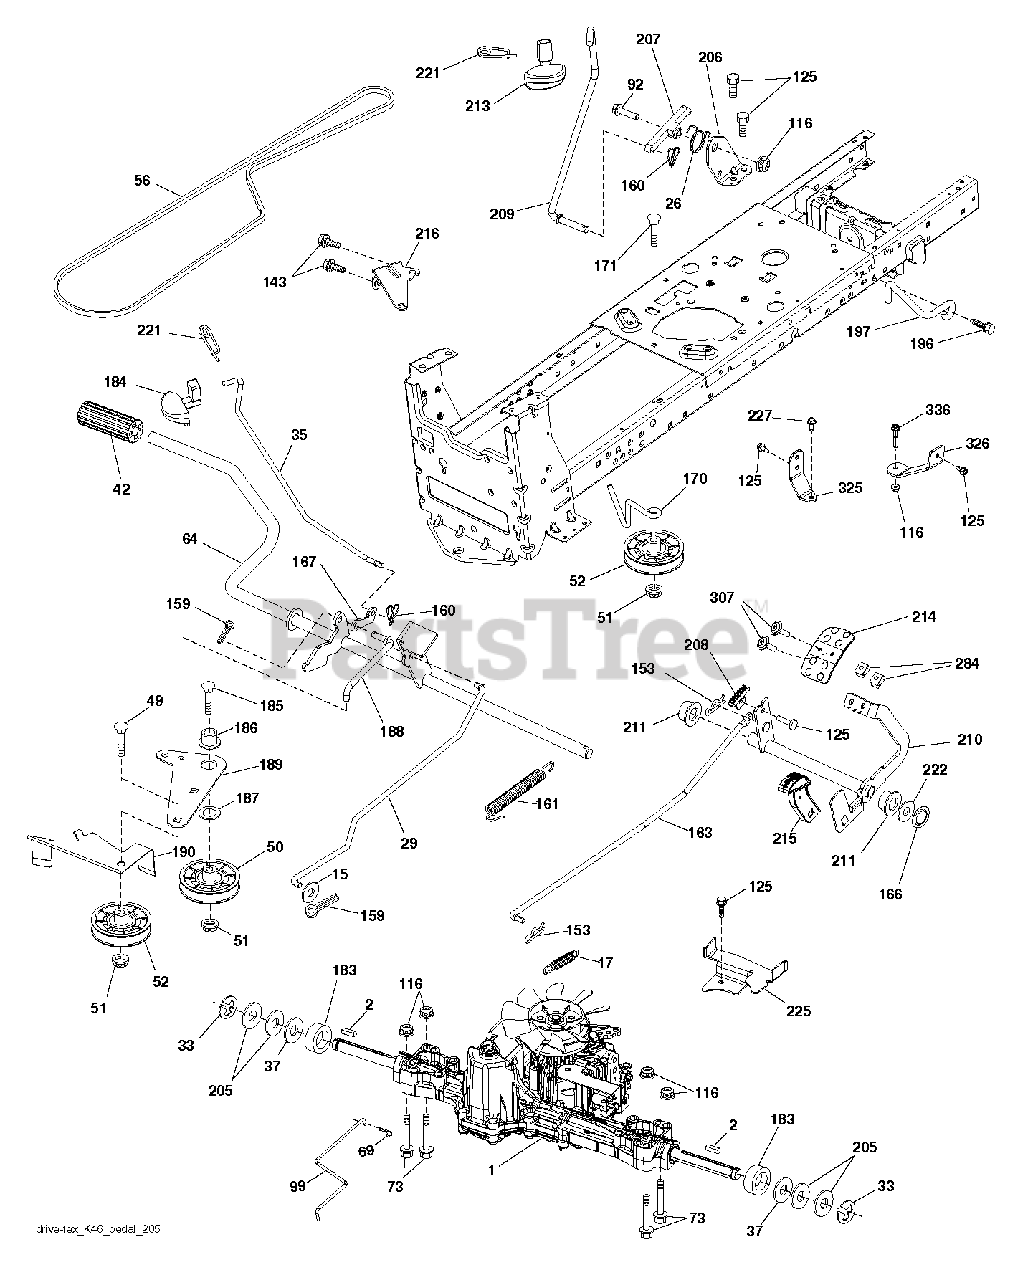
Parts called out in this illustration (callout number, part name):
2	SQUARE KEY
15	WASHER
17	SPRING.BRAKE.K46.GREEN
26	SPRING.RETURN.CRUISE
29	ROD.BRAKE.K46
35	ROD .BRAKE. PARKING. GT. HUSQ.
37	WASHER.HARDENED
42	PEDAL COVER T
50	IDLER.FLAT.910.OFFSET
51	NUT LOCK FLG 3/8-16 UNC
52	IDLER.V-GROOVE.910.OFFSET
56	V-BELT.MOWER.92.40.42/K46
64	SHAFT.ASM.PEDAL.BRK.CNTR
69	HAIRPIN.SOFT.ZINC.059X1.125
92	BOLT
99	ARM.PIVOTING.TCRD.GEN2.5.BAGGE
116	NUT LOCK HEX FLANGE 5/16-18
125	SCREW
143	SCREW LT
153	RETAINER M
159	COTTER PIN
160	RETAINER CLIP
161	SPRING, RETURN LT
163	ROD.CONTROL.K57R.K46
166	NUT.PUSH.625
167	LATCH.BRAKE.SPRING
170	KEEPER.V-IDLER.CENTER.
183	SPACER AXLE
184	HANDLE.PARKING.BRAKE.H (BLK)
186	SPACER.RETAINER
187	WASHER 12/32X2X10GA
188	RP LINK.CLUTCH.GROUND.DRIVE
189	BELLCRANK.GROUND.DRIVE.TEX.
190	KEEPER.BELLCRANK.DRIVE
196	SCREW 3/8-16X1
197	CLUTCH.ANTIROTATION.WIREFORM.
206	BRACKET.MOUNT.CRUISE.LATCH
207	LATCH.CONTROL.CRUISE.TEX
208	GEAR.SECTOR.CONTROL.CR
209	ROD.CONTROL.CRUISE.GT.
210	ROCKER.ASM.PEDAL.CONTR
211	BEARING.NYLON
213	KNOB.CONTROL.CRUSIE.HU
214	PEDAL.FORWARD.HUSQVARNA.DEALER
215	PEDAL.REVERSE.TEX.GT.4
216	BRACKET.PULLEY.IDLER.W/TEX
221	RETAINER.SPRING.CLIP.H
222	WASHER 21/32 X 1-1/4 X 10 GA.
225	KEEPER.BELT.TRANSAXLE.K46
227	SCREW
284	NUT.U-CHNL.1/4-20.550DP.350PNL
307	SCREW.MACHINE.CR.1/4-20
325	BRACKET.TRQ.STP.46.20".TIRE.LH
326	BRCKT.PNT.TRQ.STP.46.20TIRE.RH
336	BOLT.5/16-18X1-3/4.FLANGED.HEX
